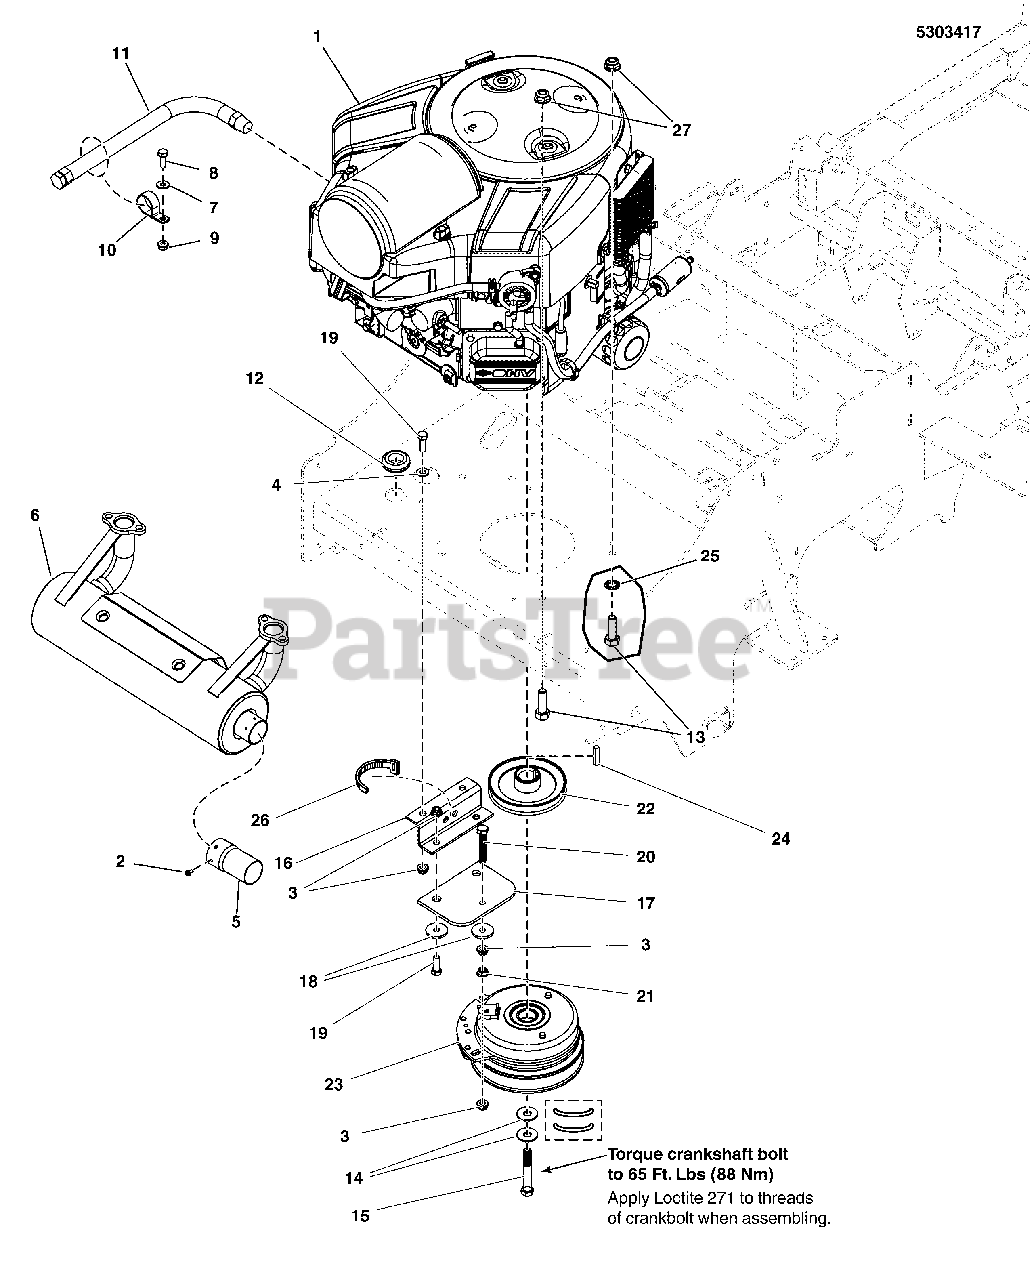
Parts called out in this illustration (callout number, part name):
1	ENGINE, 25HP B&S COMM TURF 1 X 3.16, Mod. 44T877-9322-60
2	SCREW, SELF-TAP,#8-32 X 3/8,WASH HEX, CZ
3	NUT, 5/16-18 HEX NYLOCK FLANGE
4	WASHER, 5/16 SAE
5	EXTENSION, TAILPIPE, 3" - BLACK
6	MUFFLER, RIGHT OUTLET ASSY
7	WASHER, Flat, 1/4
8	BOLT, 1/4-20 X 3/4 GD5 YZ
9	NUT, Nylock Flanged, 1/4-20
10	CLAMP, VINYL INSULATED
11	HOSE, OIL DRAIN
12	GROMMET, 7/8
13	BOLT, 5/16-24 X 1-3/4, GD8, PHOS
14	BELLEVILLE WASHER, 1.1875 X .442 X .089
15	BOLT, CRANKSHAFT, 7/16-20 X 3, GD8
16	ANCHOR, CLUTCH - BLK
17	CLUTCH ANCHOR PAD
18	WASHER, .34 X 1.25 X 10 GA
19	CAPSCREW, Hex Head, 5/16-18 x 1
20	BOLT, 5/16-18 X 2 GD5 TFL
21	NUT, Hex Serrated Flange, 5/16-18,
22	PULLEY, PUMP DRIVE, 4.857 OB X 1" BORE
23	CLUTCH, # 5219-34A, ELECTRIC, IS500Z
24	KEY, 1/4 SQ X 1
25	WASHER, 5/16 INT. TOOTH LOCK
26	TIE,SELF-LOCKING, 6"
27	NUT, 5/16-24, TOP LOCK FLANGE, GD8 PHOS
